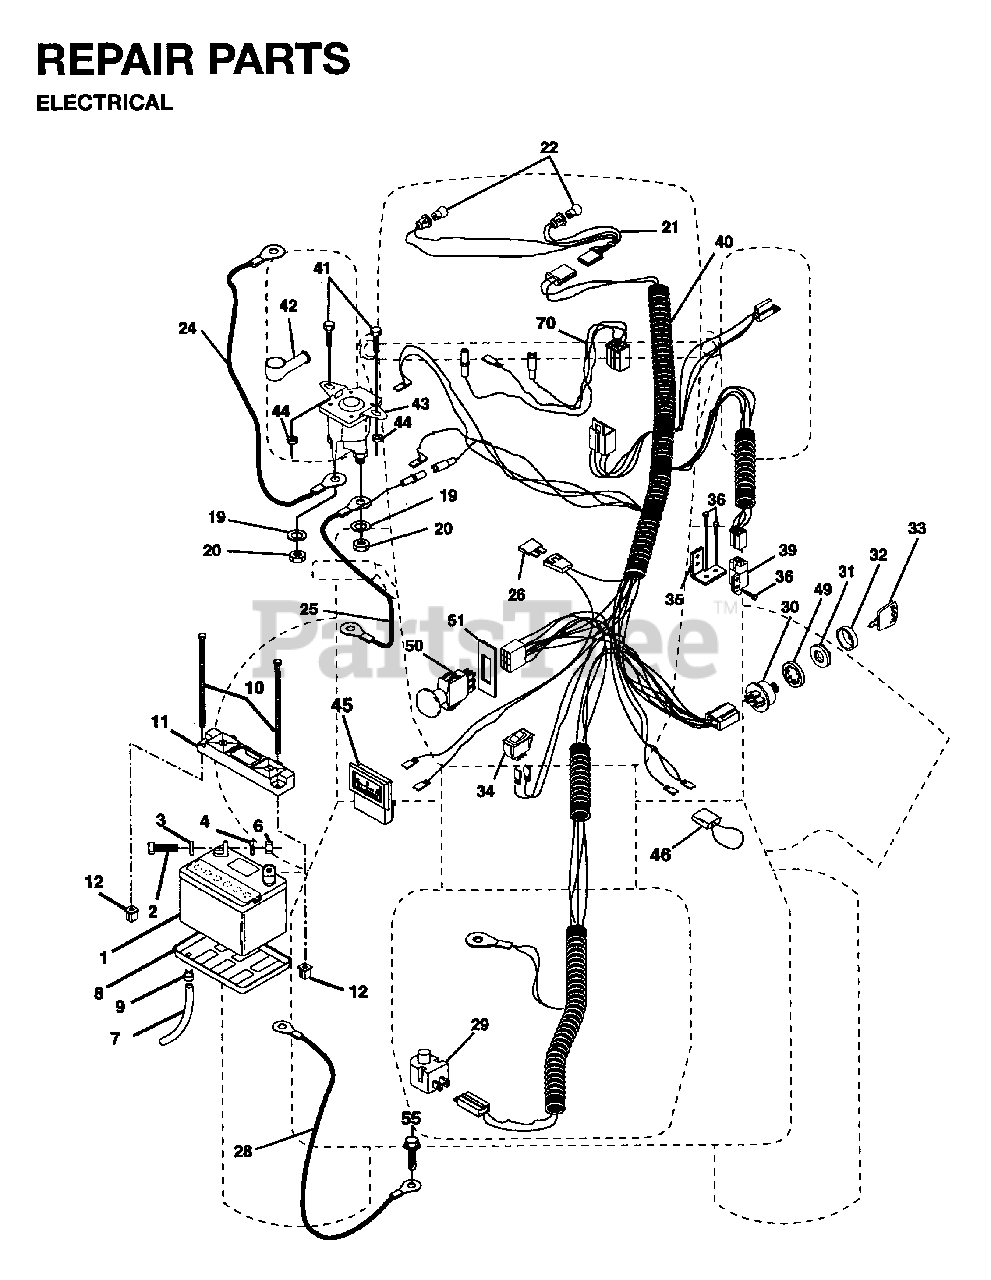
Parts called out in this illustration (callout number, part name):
1	BATTERY
4	LOCKWASHER
6	NUT
7	PLASTIC TUBE
8	TRAY.BATTERY
9	HOSE CLAMP T
10	BOLT 1/4-20 X 7.5
11	HOLDDOWN, BATTERY, DASH MOUNT
12	NUT, PUSH NYLON 1/4" BATTERY
19	LOCKWASHER
20	NUT
21	HARNESS LIGHT SOCKET
22	LIGHTBULB
25	CABLE BATTERY 6 GA 22" W/16W
28	CABLE GROUND 6 GA 21" 90T BLK
29	SWITCH SEAT
30	IGNITION SWITCH
31	NUT, IGNITION
32	COVER SWITCH KEY
33	KEY MLD GEN DELTA
34	SWITCH LT
35	BRACKET LT
39	SWITCH INTERLOCKT
40	HARNESS IGN ELECT
42	TERMINAL COVER
43	SOLINOID
44	NUT.CROWNLOCK.1/4
46	WIRE PROTECTION LOOP
49	LOCKWASHER
50	SWITCH-PTO
51	RETAINING RING
